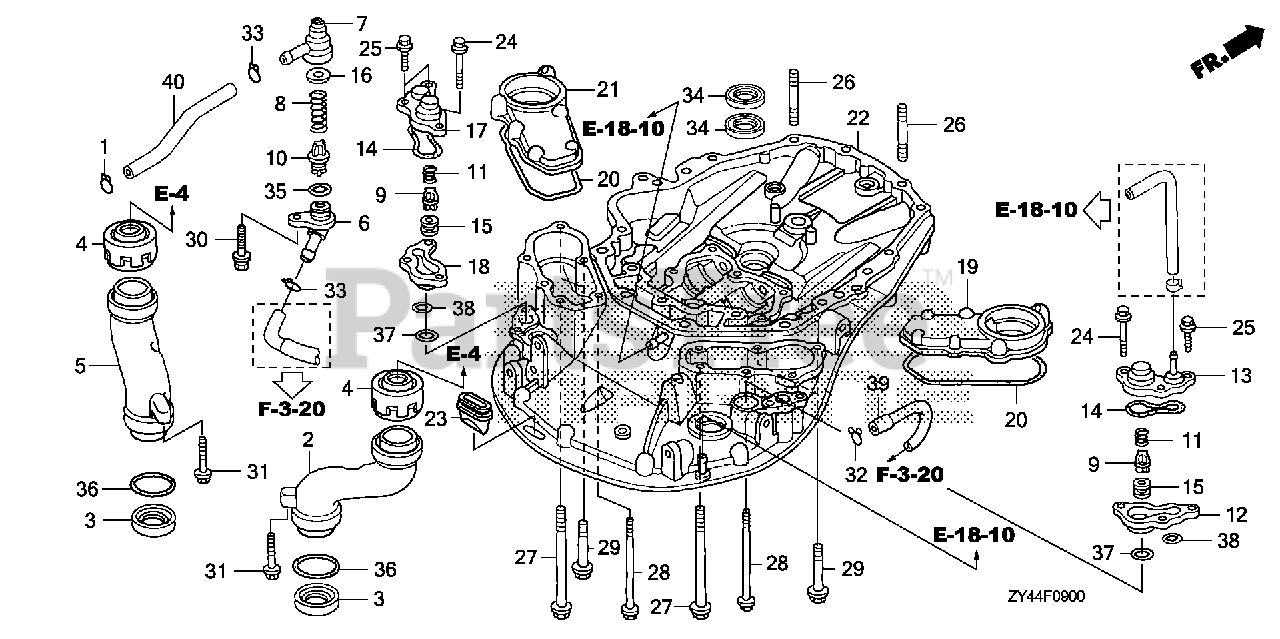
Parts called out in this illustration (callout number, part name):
1	CLIP, TUBE
2	GUIDE, R. EX. *TGRAY* (GRAY)
3	SEAL, EX. GUIDE
4	SEAL B, EX. GUIDE
5	GUIDE, L. EX. *TGRAY* (GRAY)
6	COVER, FLUSH VALVE *NH8* (DARK GRAY)
7	CASE, FLUSH VALVE
8	SPRING, FLUSH VALVE
9	VALVE, RELIEF
10	VALVE, FLASH
11	SPRING, RELIEF VALVE
12	SPACER, R. RELIEF VALVE *TGRAY* (GRAY)
13	COVER, R. RELIEF VALVE
14	GASKET, RELIEF VALVE COVER
15	GASKET, RELIEF VALVE
16	GASKET, FLASH VALVE
17	COVER, L. RELIEF VALVE
18	SPACER, L. RELIEF VALVE *TGRAY* (GRAY)
19	COVER, R. WATER JACKET *NH8* (DARK GRAY) (NOT AVAILABLE)
20	GASKET, WATER JACKET COVER
21	COVER, L. WATER JACKET *NH8* (DARK GRAY)
22	CASE, MOUNT *NH8* (DARK GRAY)
23	RUBBER, MOUNT CASE SEAL
24	BOLT, FLANGE (6X22)
25	BOLT, FLANGE (6X32)
26	BOLT, STUD (10X45)
27	BOLT, FLANGE (8X100)
28	BOLT-WASHER (6X121)
29	BOLT, FLANGE (8X30)
30	BOLT-WASHER (6X29)
31	BOLT, FLANGE (6X40)
32	CLIP, TUBE (B10)
33	CLIP, TUBE (B12.5)
34	SEAL, WATER (22X35X7)
35	O-RING (16MM)
36	O-RING (49.4X3.1)
37	O-RING (33.5X2)
38	O-RING (23.5X2)
39	TUBE, WATER CHECK
40	TUBE, FLUSH VALVE
